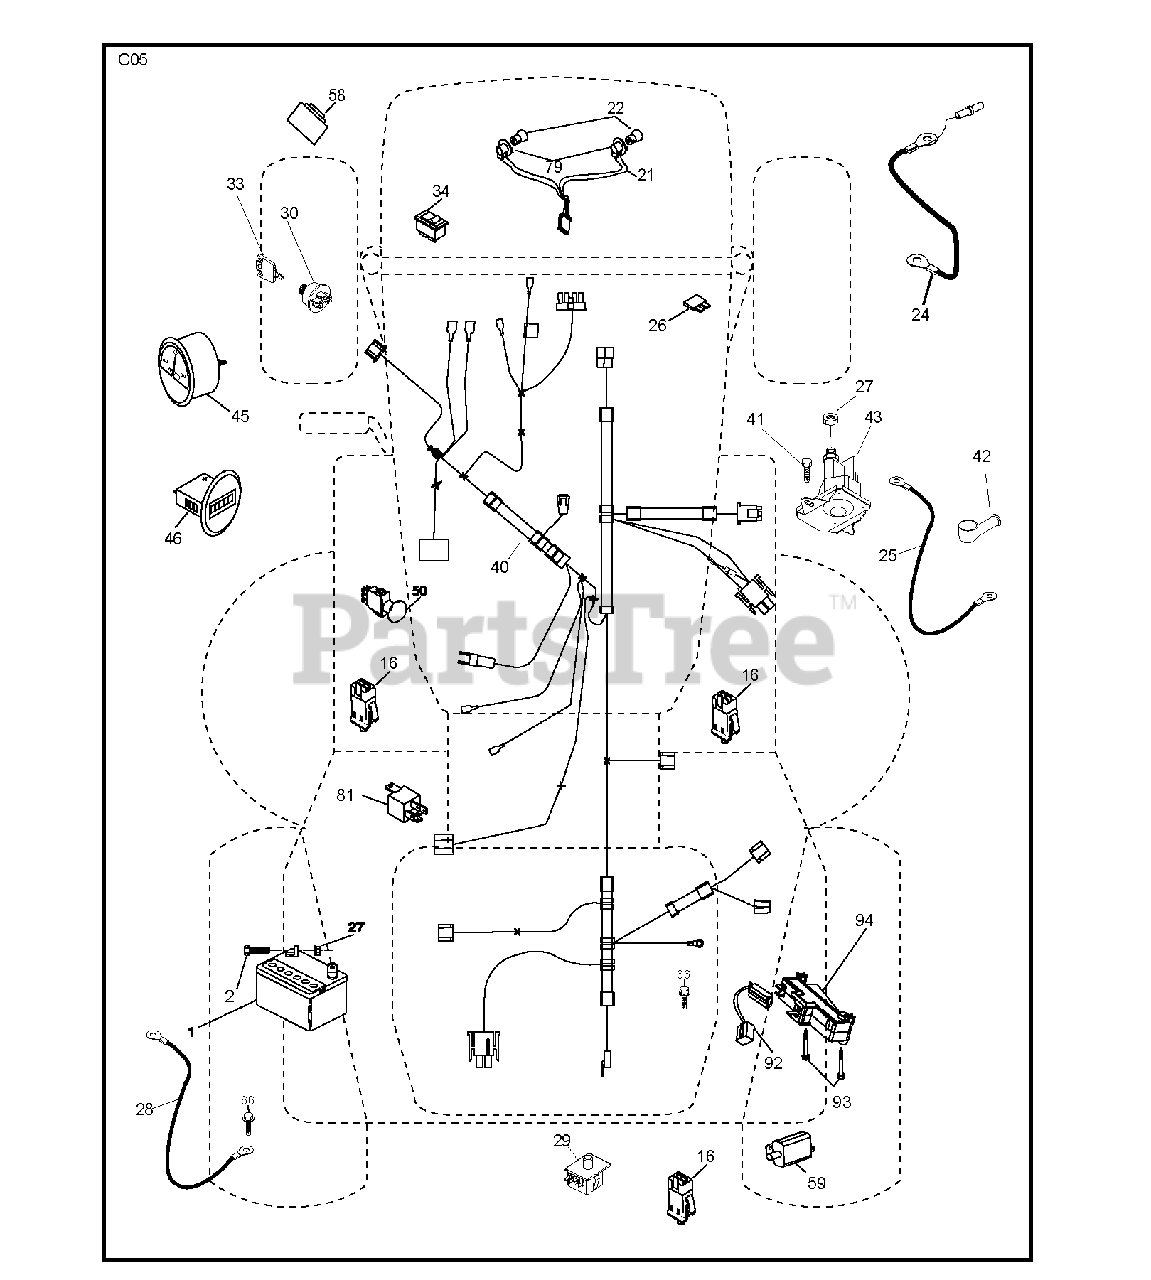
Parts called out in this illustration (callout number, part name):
1	REPL BY 532 12 38-99
16	SWITCH INTERLOOK PUSH-IN
21	HARNESS.W/LIGHT SOCKET
22	LIGHTBULB
24	CABLE BATTERY 6 GA. 11" RED
25	CABLE BATTERY
26	FUSE 20AMP
27	NUT
28	CABLE GROUND
29	SWITCH.SEAT.DP W/RAMPS
30	SWITCH.IGN.DELTA.W.LGH.ROS
33	KEY.CHAIN.BLISTER.PACK.GEN.INT
34	SWITCH LT
42	TERMINAL COVER
43	SOLENOID.W/BRASS.PLUNG
50	PTO SWITCH
58	BUZZER
79	BULB HOLDER ASM.
81	RELAY.ASSY.T
92	HARNESS.PIGTAIL.CONSLE
93	SCREW.PLASTITE
94	MODULE.REVERSE.ROS
103	NUT.10-32.EXTLOCK
104	HARNESS.JUMPER.GAUGES
